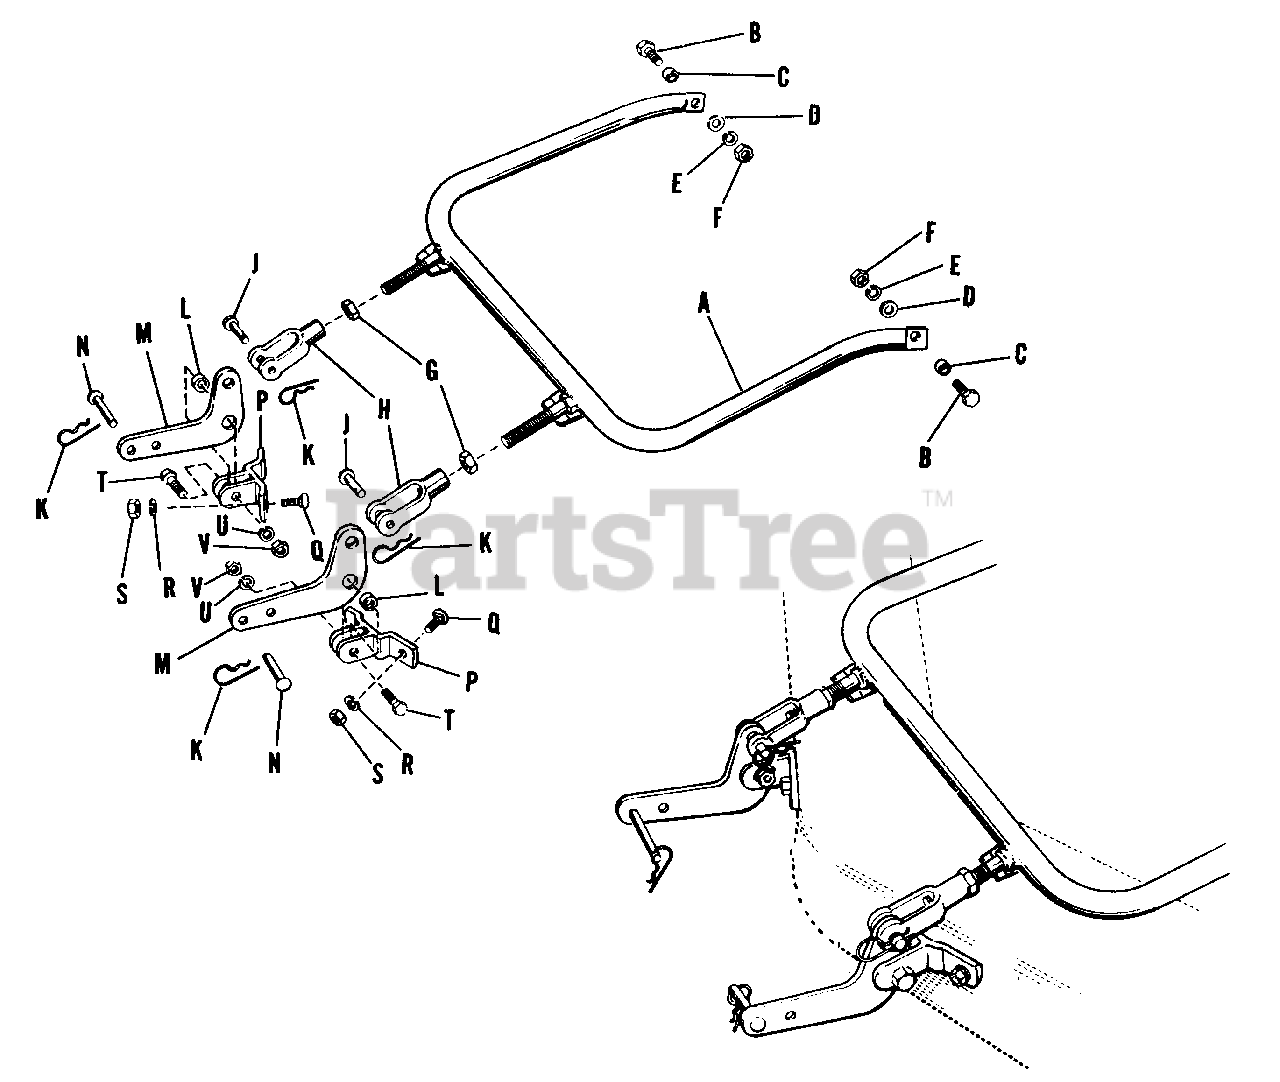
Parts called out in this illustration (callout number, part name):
A	Bail Assembly
B	Capscrew, Hex Hd., 1/2"-13 NC x 1 1/4" lg.
D	Washer, Plain, 7/16
E	Washer, Lock, 1/2"
F	Nut, Hex, Full, 1/2"-13 NC
G	Nut, Hex, Jam, 1/2"-20 NF
H	Yoke End, Adjusting
K	Clip, Spring
M	Rocker Arm
N	Pin
P	Bracket Assembly, Front
Q	Bolt, Carriage, 3/8"-16 NC x 1"
R	Washer, Lock, 3/8"
S	Nut, Hex, Full, 3/8"-16 NC
T	Capscrew, Hex, 1/2"-13 NC x 1 1/4"
U	Washer, Lock, 1/2"
V	Nut, Hex, Full, 1/2"-13 NC
